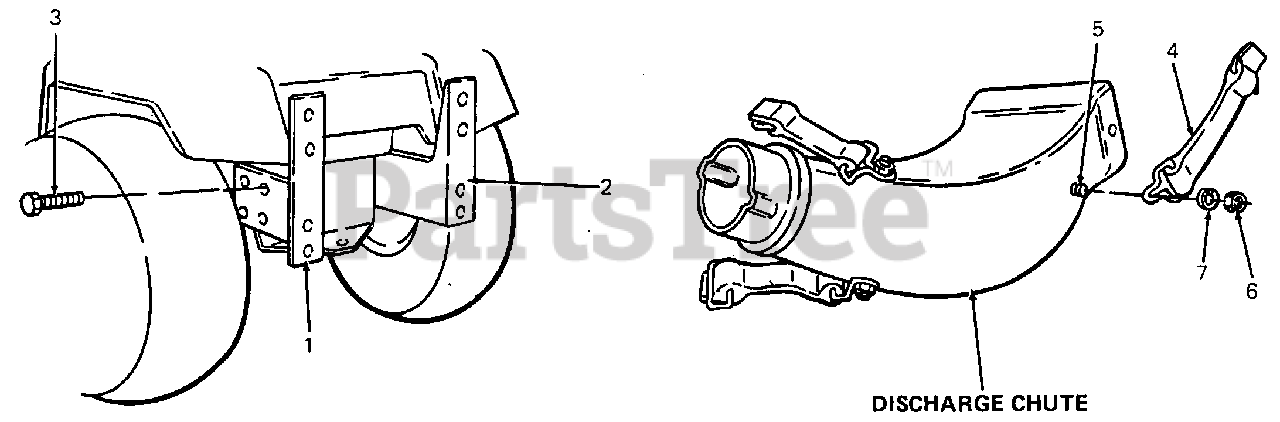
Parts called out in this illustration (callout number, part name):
1	Bracket, LH - Bagger Support
2	Bracket, RH - Bagger Support
3	Screw, Hex Cap, 3/8-16 X 1.0 Lg GR 5
4	Strap Assy, Retainer
5	Screw, Hex Cap, 1/4-20 X .62 Lg
6	Nut, Hex Insert Lock, 1/4-20
7	Washer, Spring, .265 ID X .562 OD
